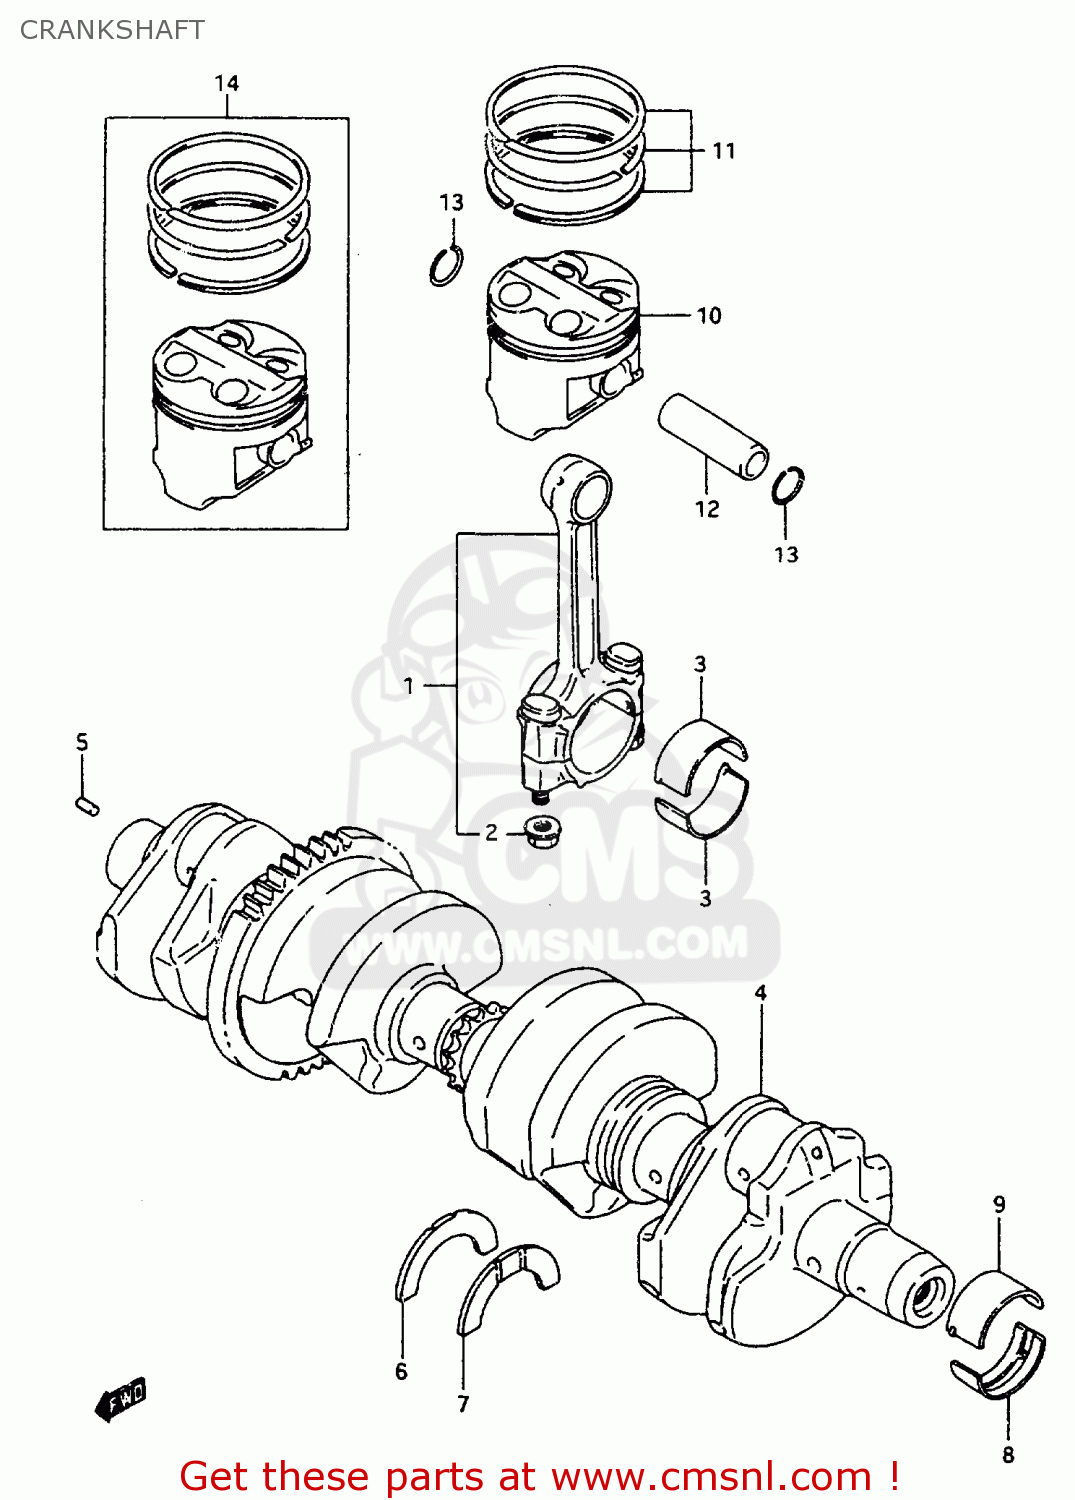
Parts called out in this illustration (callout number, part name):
1	ROD ASSEMBLY,CONNECTING
2	NUT
3	BEARING,CRANK PIN
4	CRANKSHAFT SET
5	PIN
6	PLATE,CRANK THRUST
7	PLATE,CRANK THRUST
8	BEARING,CRANKSHAFT LWR
9	BEARING,CRANKSHAFT UPR
10	PISTON
11	RING SET,PISTON
12	PIN,PISTON
13	CIRCLIP
14	PISTON SET(OS:0.5)
